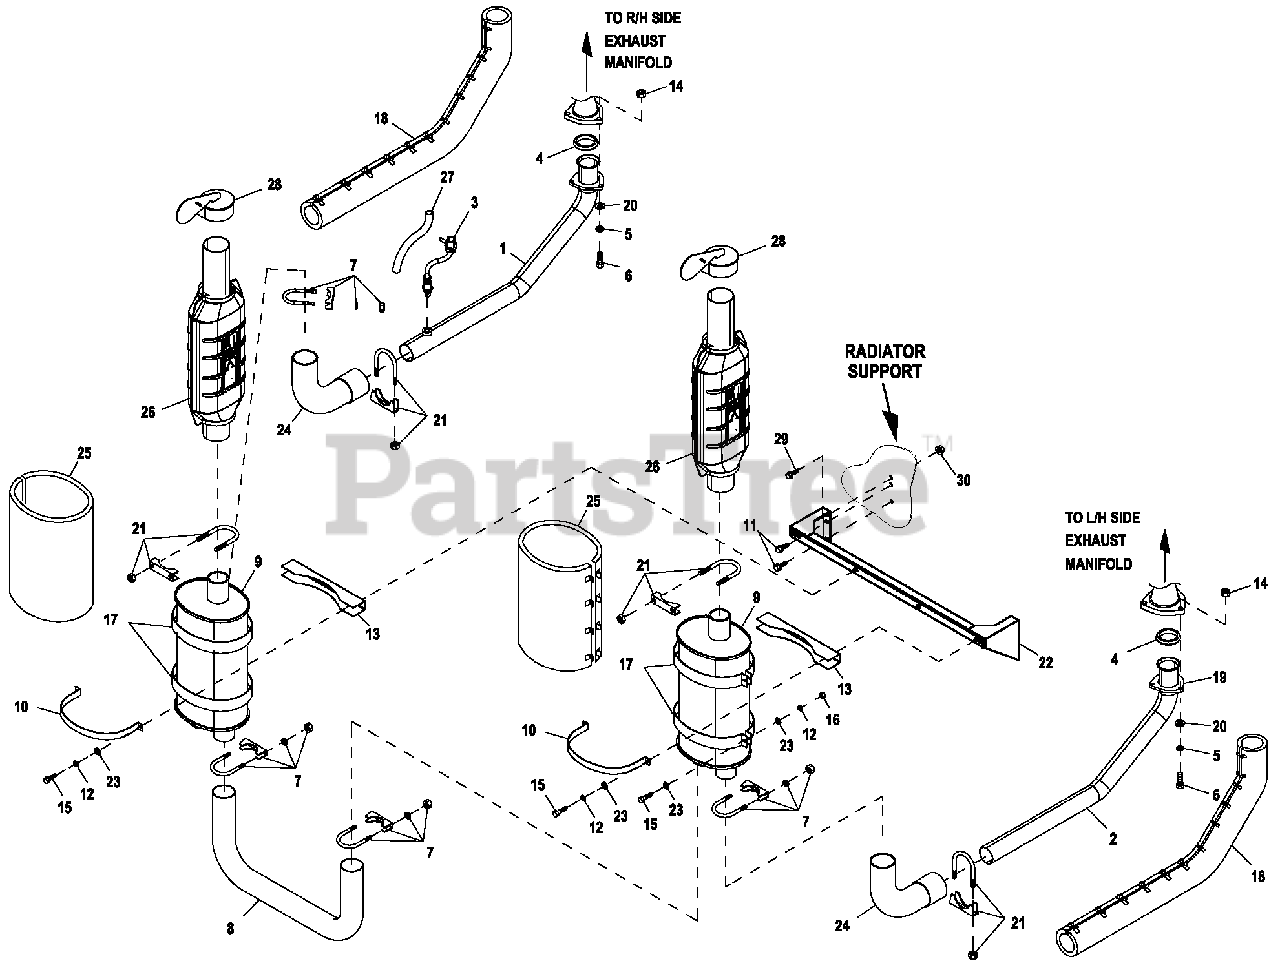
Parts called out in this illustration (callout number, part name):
1	PIPE.EXH MAN R/H 6.8L LSI CPL
2	PIPE.EXH MAN L/H 6.8L LSI CPL
3	SENSOR OXYGEN
4	RING GASKET 2.5 DIA
5	WASHER LOCK M10SS
6	SCREW HHC M10-1.5X 50 SS FTH
7	BOLT U 3/8-16 X 3.00" W/SADDLE
8	PIPE EXHAUST CROSSOVER
9	MFLR 7" X 9" X 25" (2) 2.5" IN/2.5" OUT
10	MUFFLER STRAP
11	SCREW THF M6-1 X 16 N WA Z/JS
12	WASHER LOCK M6-1/4
13	MUFFLER BRACKET STIFFENER
14	NUT HEX M10-1.5 SS
15	SCREW HHC M6-1.0 X 35 G8.8 BLK
16	NUT HEX M6 X 1.0 G8 YEL CHR
17	MUFFLER STRAP UPPER/LOWER
18	EXHAUST BLANKET 900MM LONG
19	FLANGE EXHAUST
20	WASHER FLAT 3/8 SS
21	BOLT U 3/8-16X2.62
22	BRKT MUFFLER
23	WASHER FLAT 1/4-M6 ZINC
24	PIPE ELBOW EXHAUST MUFFLER
25	BLANKET EXHAUST MUFFLER 584MM
26	CATALYST 3-WAY
27	REFLEX WRAP 13MM 13X460 (12"LG)
28	RAINCAP 2-1/2" AL
29	SCREW HHFC M6-1.0 X 20 G8.8
30	NUT FLANGE M6-1.0 NYLOK
